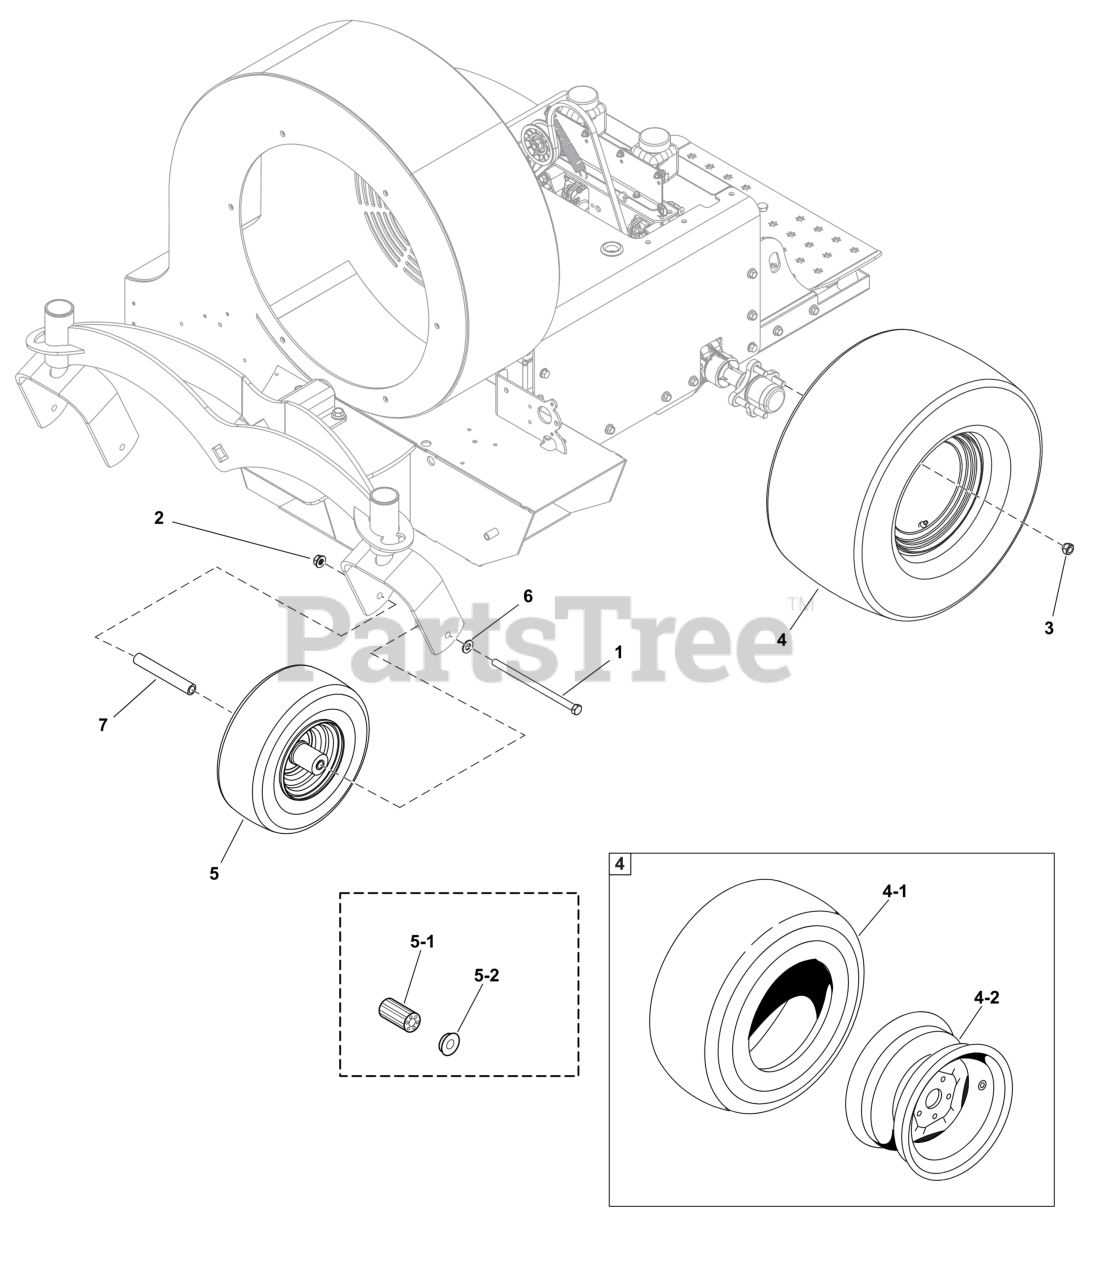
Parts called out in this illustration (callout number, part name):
1	BOLT, 1/2-13 X 7 GD5
3	NUT, 1/2-20, FOR WHEEL BOLT SILVER
4	TIRE ASSEMBLY
4-1	TIRE, 20-8 x 8 4PLY (TIRE ONLY)
4-2	WHEEL RIM
5	TIRE ASSEMBLY
5-1	BEARING, CASTER WHEEL, 11 X 4.0 - 5 BEAD LOCK (SV)
5-2	RETAINER, BEARING (TWO PER TIRE)(SV)
6	WASHER, 1/2" SAE
7	CASTER AXLE DDSH
